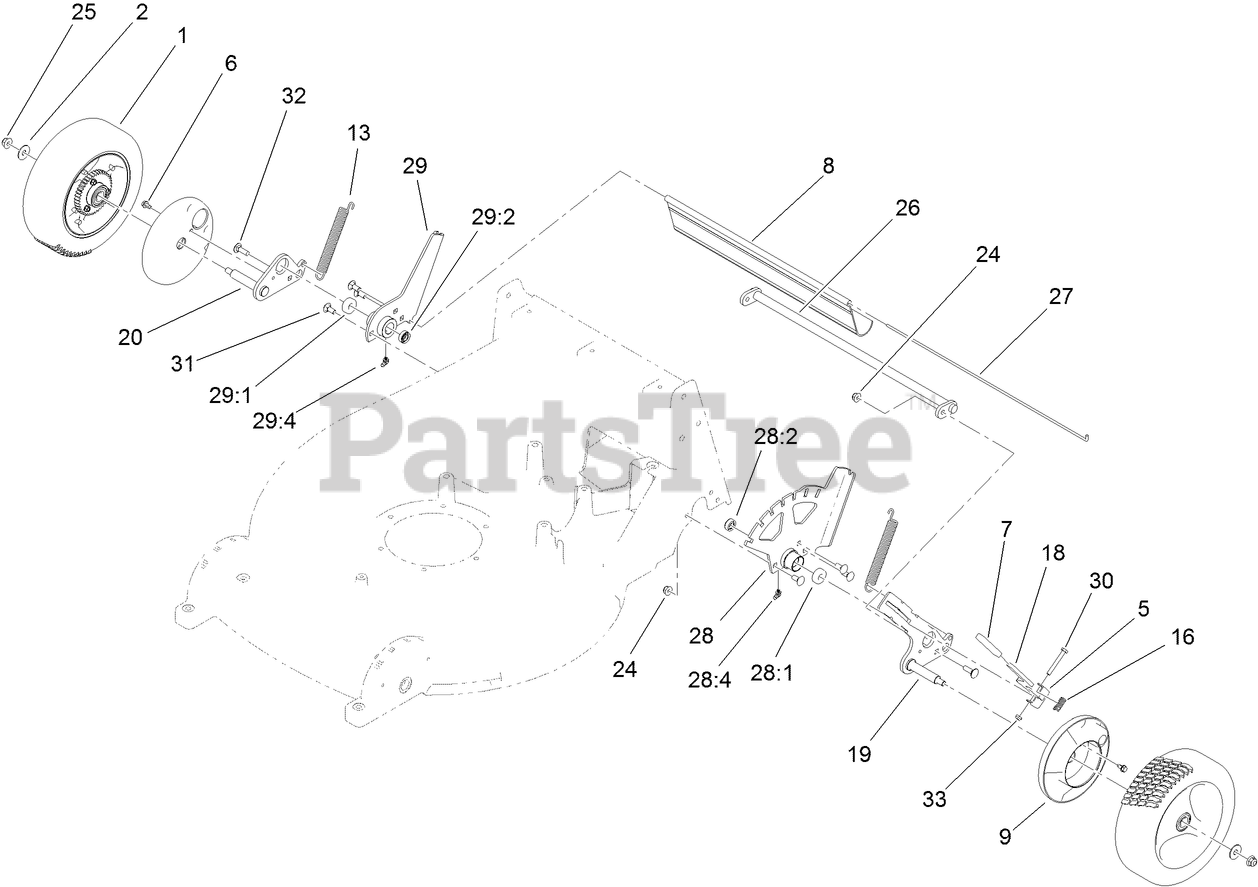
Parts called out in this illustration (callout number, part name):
1	10 INCH WHEEL ASM
2	WASHER
5	BRACKET-PIVOT, LIFT
6	SCREW
7	COVER-HANDLE
8	SHIELD-REAR
9	COVER-GEAR
13	SPRING-ASSIST, LIFT
16	SPRING-LATCH
18	LEVER-LIFT
19	ARM-AXLE, LH
20	ARM-AXLE, RH
24	NUT-HF, NI
25	NUT-HF, NI
26	ROD-TORQUE
27	ROD-SHIELD
28	LH BEARING SUPPORT ASM
28:1	BEARING-AXLE, REAR
28:2	SEAL-AXLE
28:4	FITTING-GREASE
29	RH BEARING SUPPORT ASM
29:1	BEARING-AXLE, REAR
29:2	SEAL-AXLE
29:4	FITTING-GREASE
30	SCREW-HH
31	BOLT-CARR
32	BOLT-CARR
33	NUT-LOCK, NI
